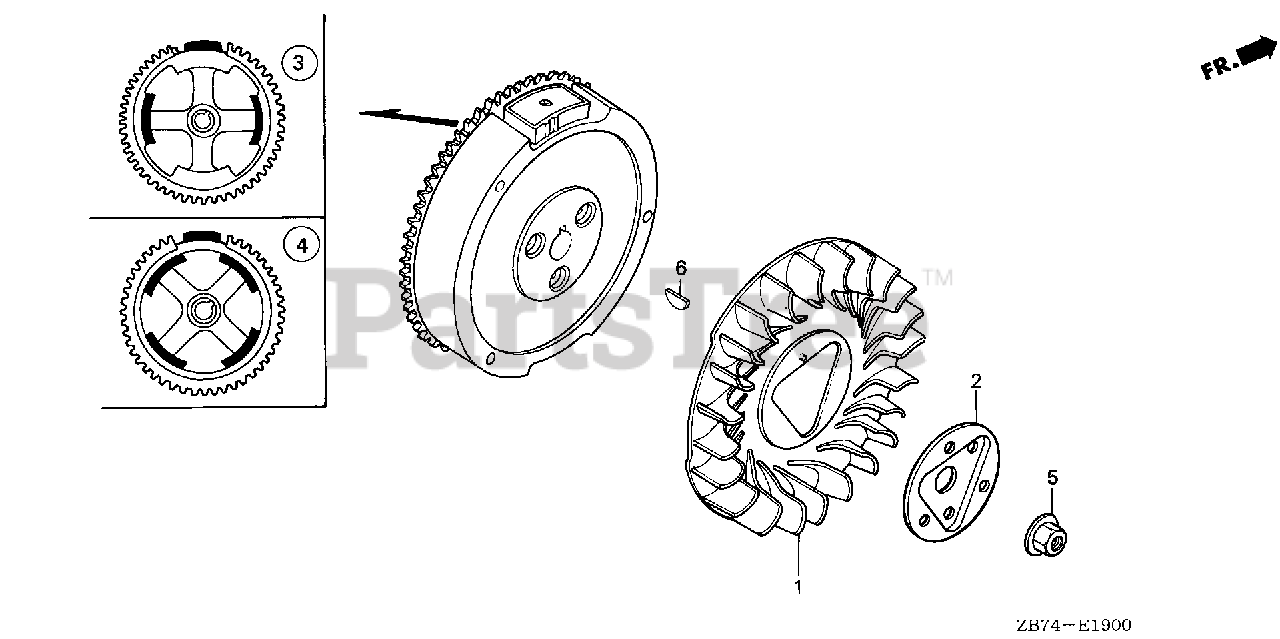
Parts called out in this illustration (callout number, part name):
1	FAN, COOLING
2	PLATE, COOLING FAN SETTING
3	FLYWHEEL (STARTER MOTOR)
5	NUT, SPECIAL (16MM) (1)
6	KEY, SPECIAL WOODRUFF (25X18)
